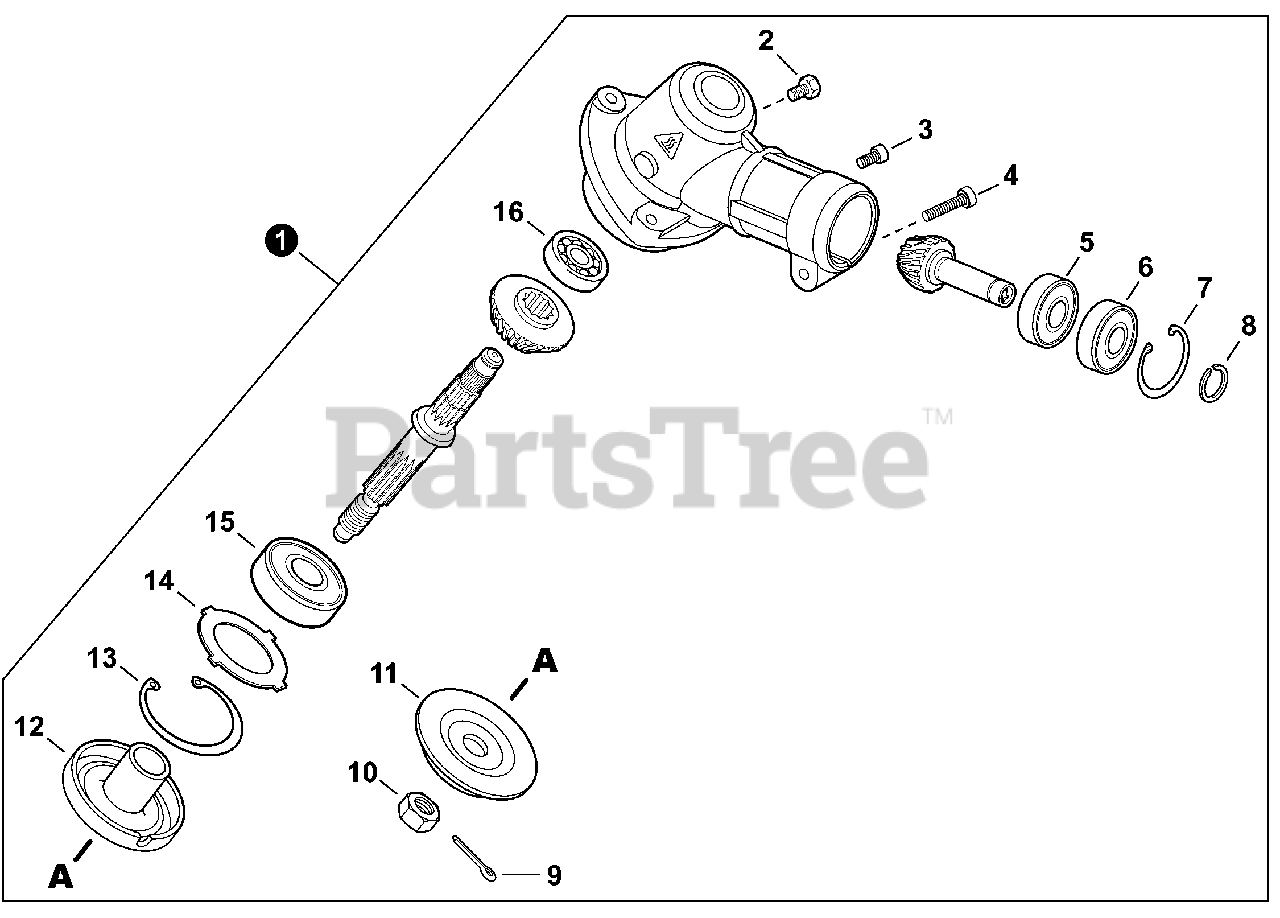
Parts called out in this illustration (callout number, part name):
1	GEAR CASE ASSY
2	BOLT M8×8
3	BOLT, TORX 5×10
4	BOLT, TORX 5×25
5	BEARING, BALL 609
6	BEARING, BALL 609
7	RING, SNAP Ø25
8	RING, SNAP Ø9
9	PIN, COTTER 2×22
11	PLATE, ADAPTOR - LOWER
12	PLATE, ADAPTOR - UPPER
13	RING, SNAP Ø32
15	BEARING, BALL 6201
16	BEARING, BALL 629
